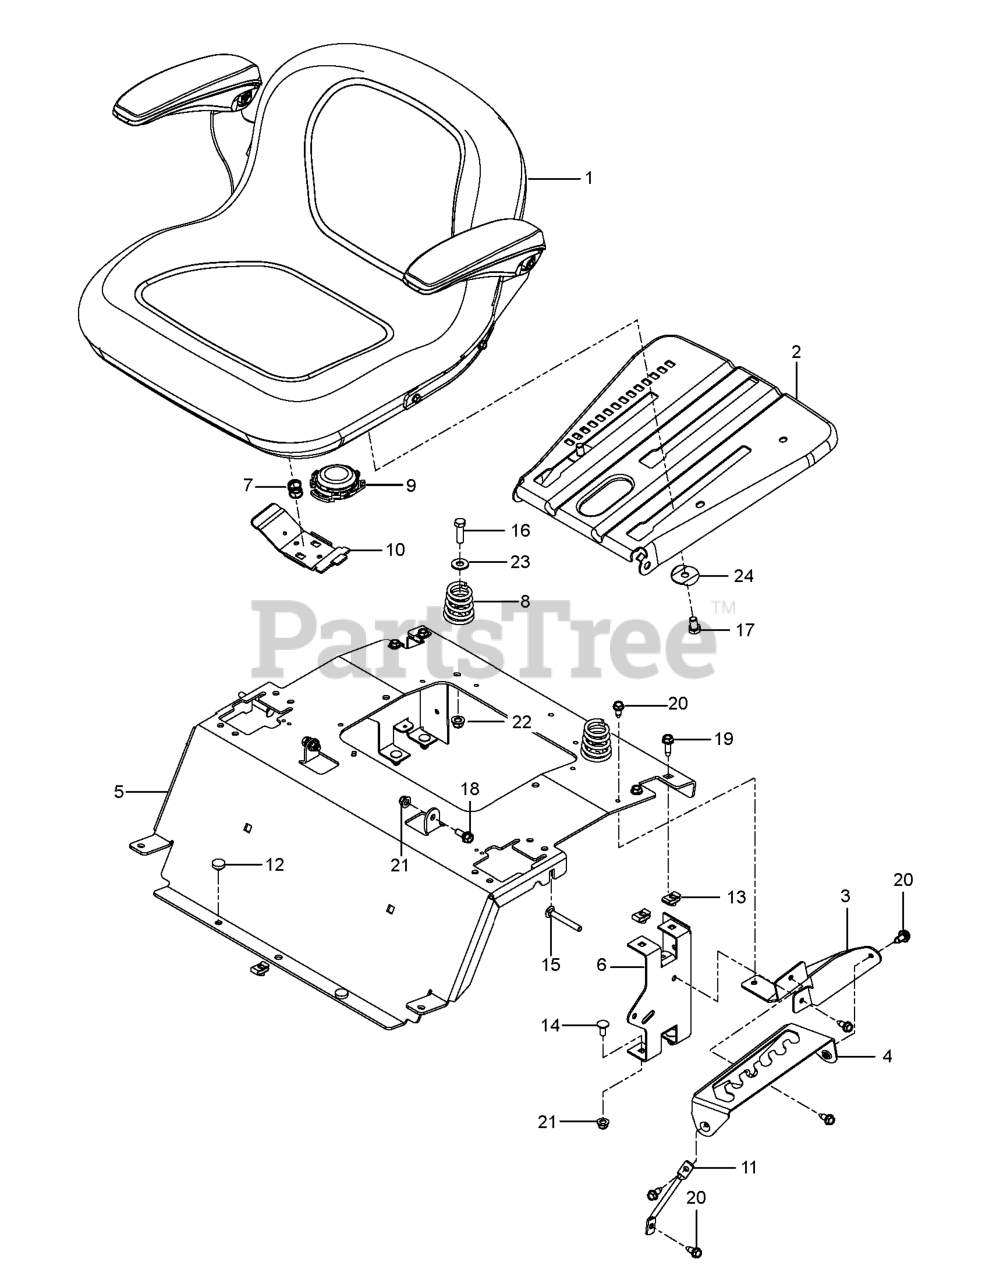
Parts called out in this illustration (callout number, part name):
1	SEAT.TH150.MS498.GRY.HUSQ.TEX
2	PLATE.PNT.SEAT.SLIDE.3PT.EDIP
3	PLATE.SUPPORT.DECK.LIFT.X431
4	PLATE.DECK.LIFT.X431
5	PLATE.SUPPORT.SEAT.RZ.ORANGE
6	SUPPORT REAR SEAT BLACK
7	SPRING.LATCH.SEAT.TEX
8	SPRING.COMPRESS.SEAT.TAPERED
9	SWITCH.SEAT.DELTA.OPC.
10	HANDLE.SLIDE.SEAT.TEX.BLACK
11	SUPPORT.LEG.DECK.LIFT
12	GROMMET.BUMPER
13	U-CLIP 5/16-18 NUT RETAINER
14	RP BOLT 5/16-18 X3/4 ZN/YEL GR
15	RHSNB 5/16-18 X 2-1/2 GR5 ZD
16	BOLT
18	BOLT, SHOULDER
19	SCREW.THDROL.5/16-18X3/4.TTY
20	BOLT.5/16HEX.WHS.HD
21	5/16-18 NYLOC FLANGE NUT
22	NUT 3/8-16 HEX FLG NYLOC ZD
23	WASHER.WINGED.3/8ID.1.5OD
24	RP WASHER 3/8 FLAT
